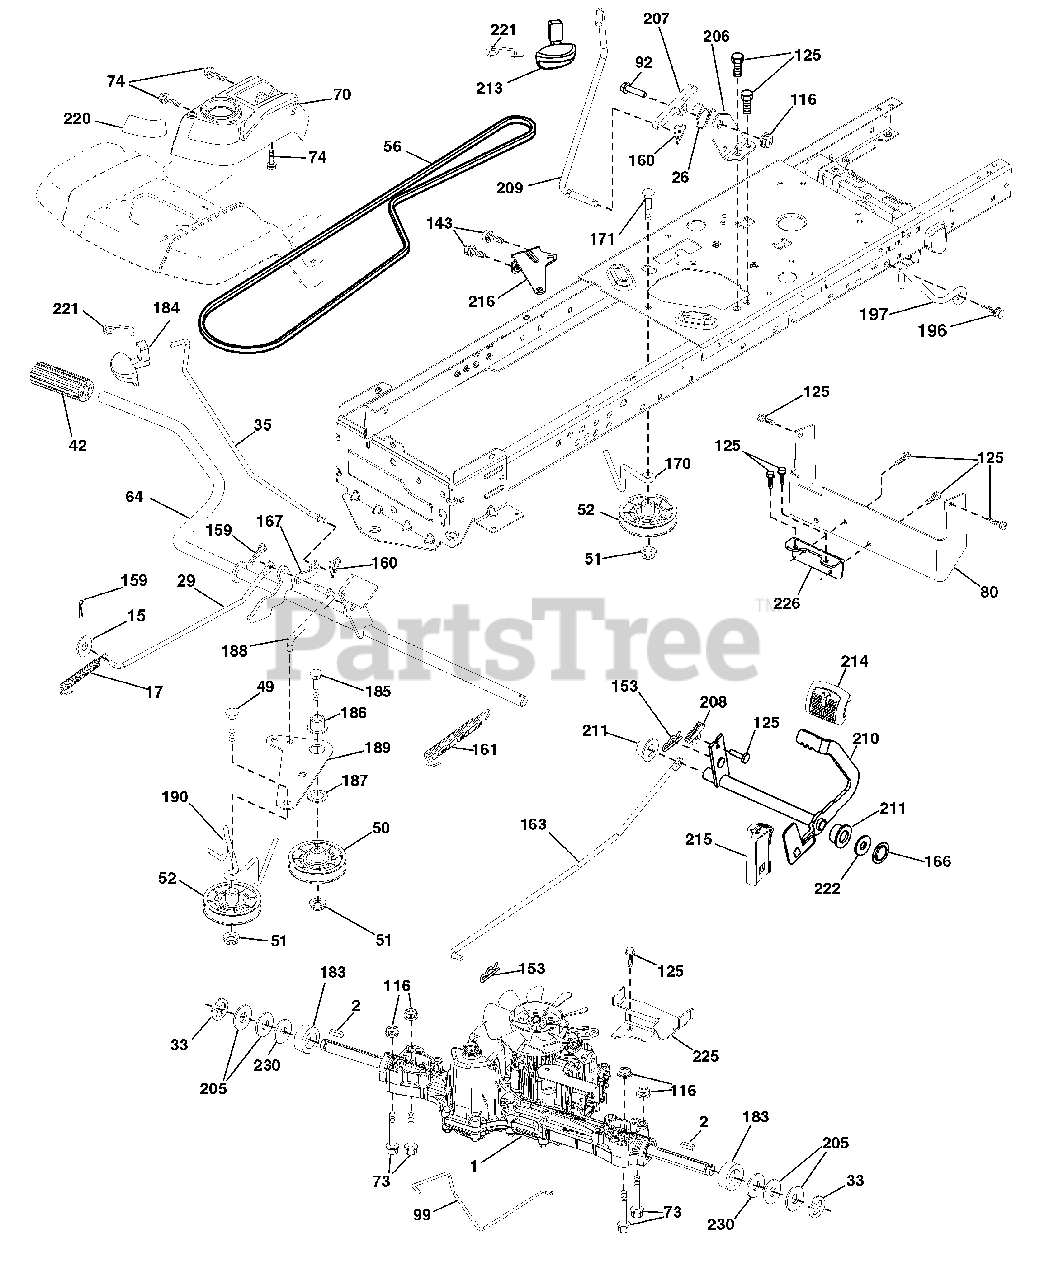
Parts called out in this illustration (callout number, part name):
1	Transaxle, TUFFTORQ K46
2	Key 1/4 x 2.5
15	Washer 13/32 x 13/16 x 16 Ga.
17	Spring, Brake
26	Spring Return Cruise
29	Rod, Brake
35	Rod, Brake, Park
42	Cover, Foot Pedal
50	Pulley Idler Flat
51	Lock Nut 3/8-16
52	Idler V-Groove 910" Offset
56	V-Belt, Drive
64	Shaft Asm. Pedal Brake Control
70	Console Asm.
73	Bolt Hex Flghd 5/16-18 x 3.75
74	Screw 1/4 x 1/2
80	Strap Torque
92	Bolt Fin Hex 5/16-18 unc x 1.25
99	Rod Spring Bypass
116	Nut Lock Hex Flange 5/16-18
125	Screw 5/16-18 x 3/4
143	Screw Thdrol 5/16-18 x 1/2
153	Retainer Spring
159	Pin Cotter 1/8 x 3/4
160	Retainer Clip
161	Spring, Return, Clutch
162	Spacer Transaxle
163	Rod Pedal Control
166	Nut Push .625
167	Latch Brake Parking
170	Keeper Belt Centerspan
171	Bolt RDHD SQNK 3/8-16 unc x 2
183	Spacer Split
184	Handle Parking Brake
185	Bolt Rdhd Sqnk 3/8-16 x 2-1/2
186	Spacer Retainer
187	Washer
188	Link Clutch Ground Drive
189	Bellcrank Ground Drive
190	Keeper Bellcrank Ground Drive
196	Screw 3/8-16 x 1
197	Bracket Clutch Anti-Rotation
206	Bracket Mount Latch Cruise
207	Latch Control Cruise
208	Gear Sector Control Cruise
209	Rod Control Cruise
210	Rocker Asm. Pedal Control
211	Bearing Nylon
213	Knob Control Cruise
214	Pedal Forward
215	Pedal Reverse
216	Bracket Pulley Idler
220	Reflector RH
221	Retainer Spring Clip Handle
222	Washer 21/32 x 1-1/4 x 10 Ga.
225	Keeper Belt Trans.
226	Bracket Mount Torque
230	Washer Harden
